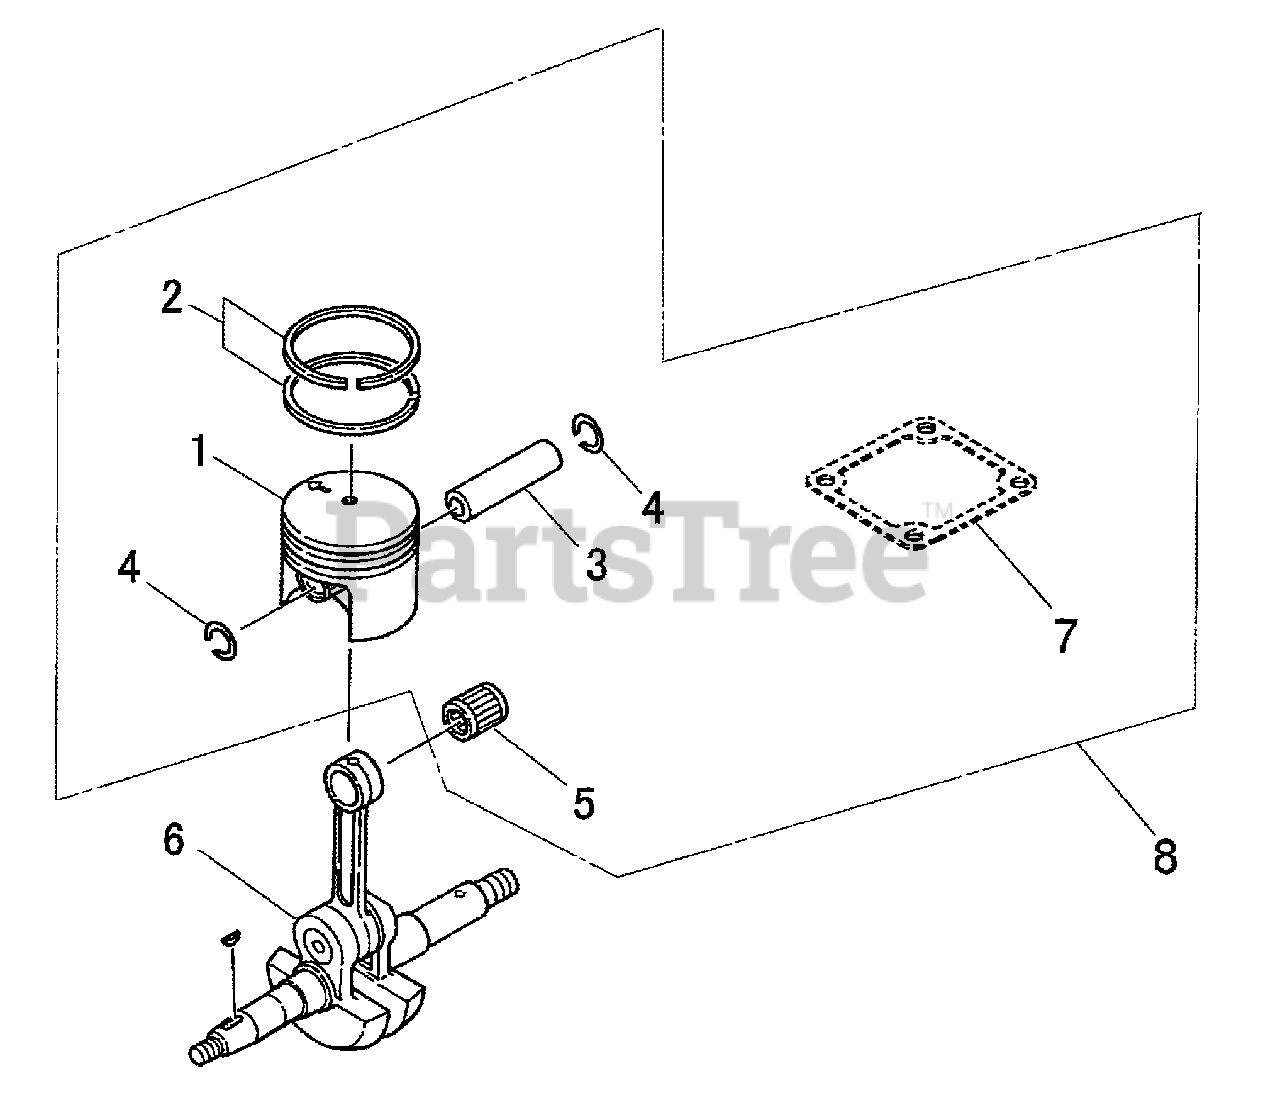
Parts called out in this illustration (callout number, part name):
1	PISTON
2	RING, PISTON
3	PIN, PISTON
4	RING, RETAINING
5	BEARING, NEEDLE
6	CRANKSHAFT ASSY
7	GASKET, CYLINDER
8	PISTON ASSY
